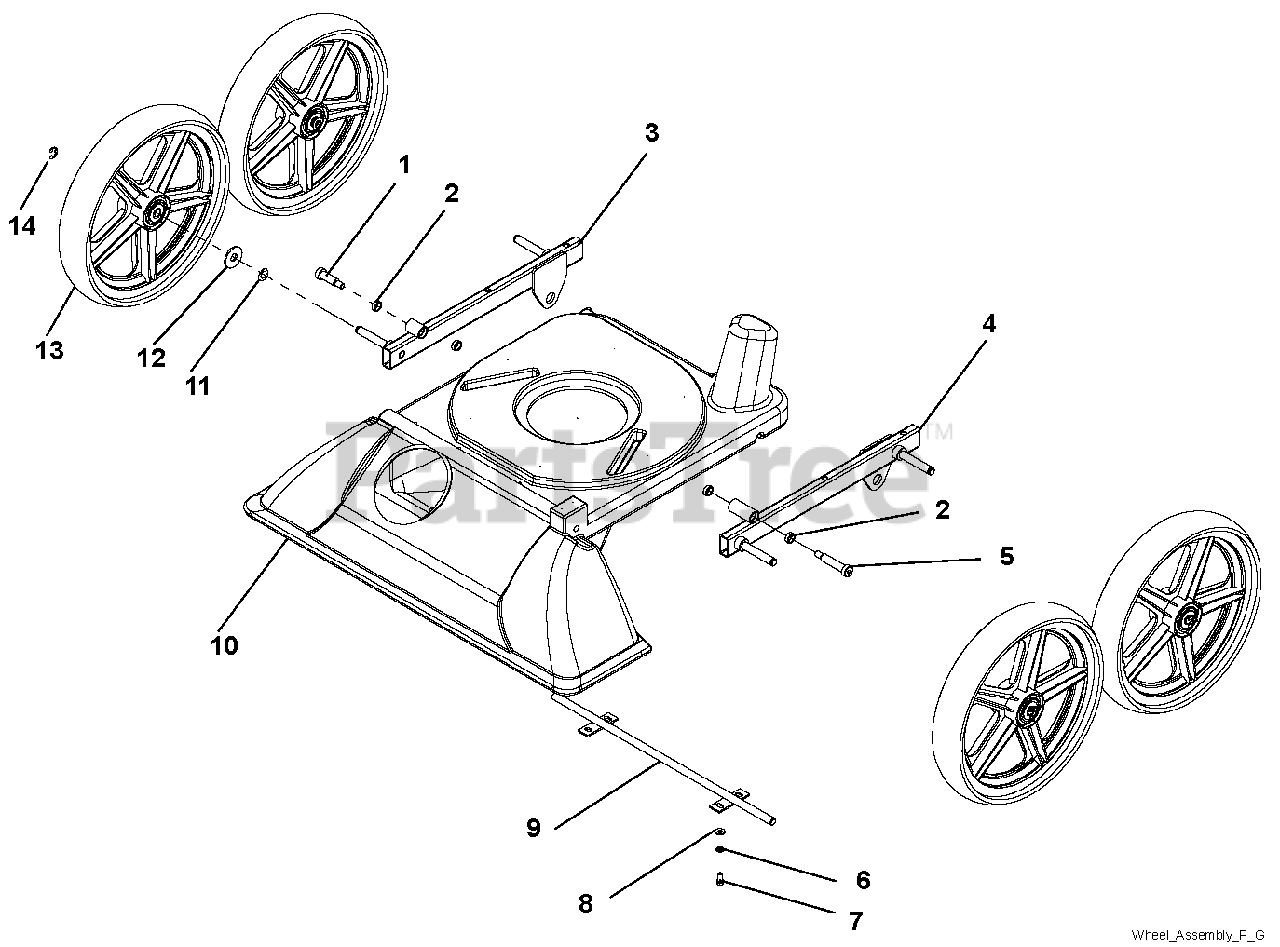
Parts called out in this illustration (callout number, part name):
1	Bolt, Shoulder .5 X 1.25 X .38-16
2	Oilite Sleeve AA-618-16
3	APV Side Rail Weldment Assembly, Right
4	APV Side Rail Weldment Assembly, Left
5	Bolt, Shoulder .5 X 2.0 X .38-16
6	Washer, Locking .25 X .062 Regular
7	Bolt, Hex .25-20 X .63
8	Washer, Flat, Steel .281 X .62 X .065
9	APV Bar, Body Adjustment
10	APV Main Housing, Parker Red
11	Washer, Wave .52 X .87 X .01
12	Washer, Flat .50 X 1.37 X .10
13	APV Wheel, Spartech 14"
14	Retaining Ring, E External .50
